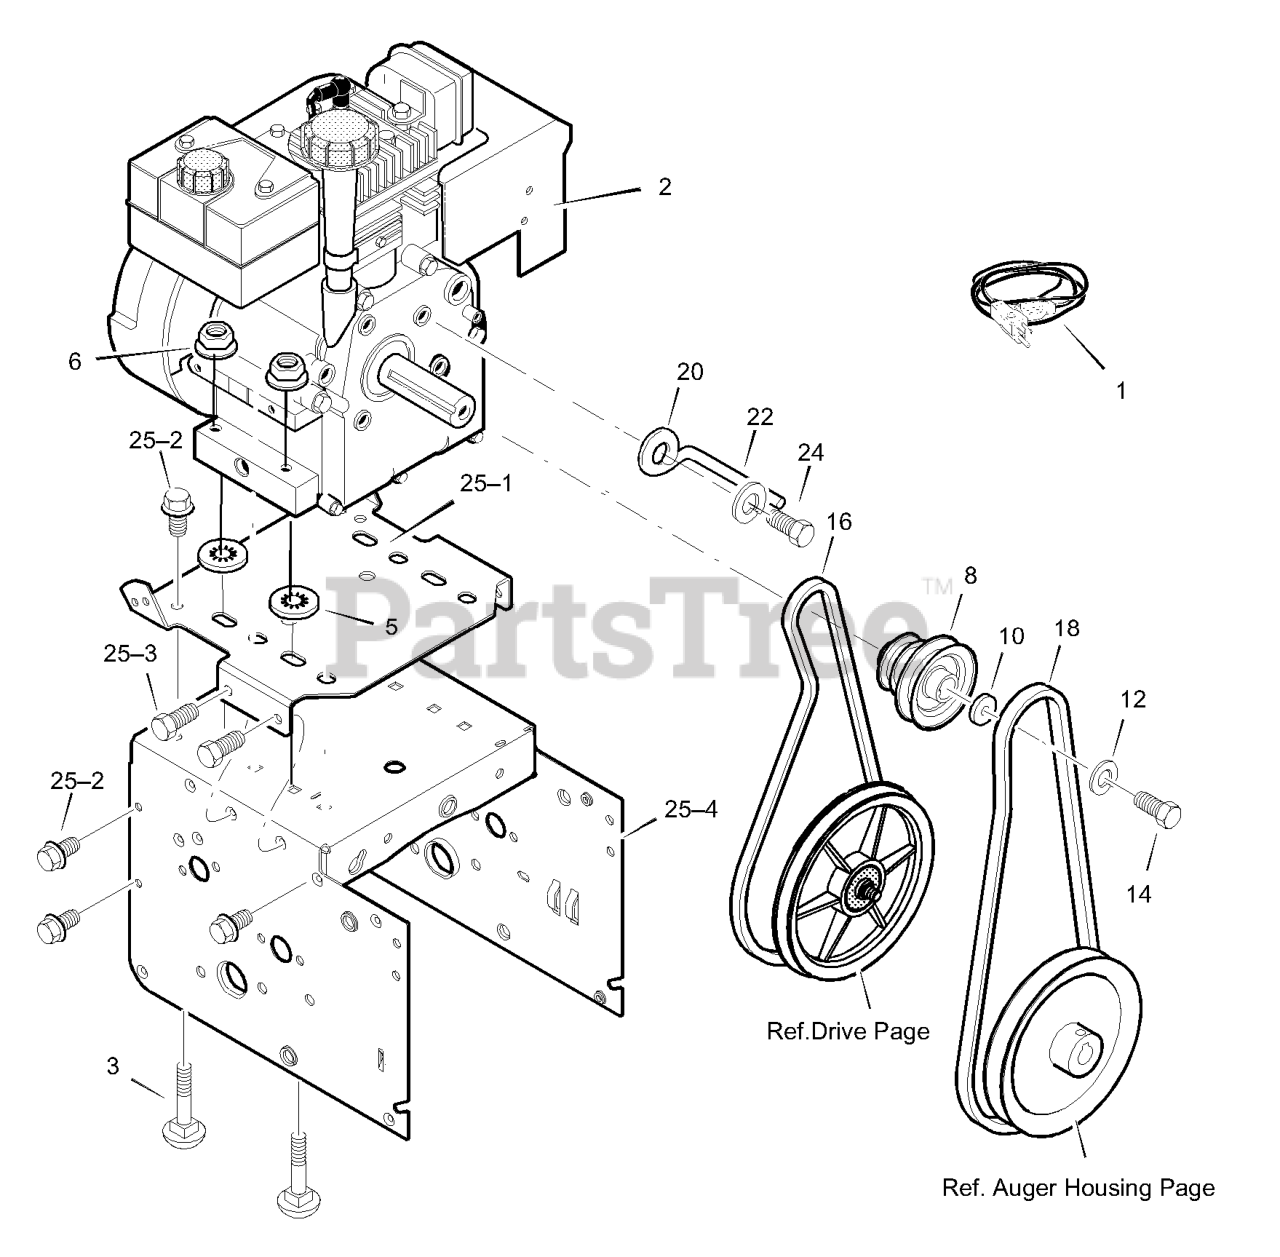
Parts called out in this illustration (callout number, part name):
1	CORD, STARTER MOTOR 220V
2	ENGINE
3	BOLT, CARRIAGE 5/16-18
5	RETAINER, PUSH
6	NUT, HEX 5/16-18
8	PULLEY, ENGINE
10	WASHER
12	WASHER .38ID
14	SCREW, 3/8-24 x 1.00
16	BELT, V 3L 33.13LG
18	BELT, V 4L 38.1MF16" 5-10
20	GUIDE, BELT
22	WASHER, SPTLK .31X.58X.08
24	SCREW, 5/16-24 x 0.75
25	FRAME ASSEMBLY
25-1	PLATE, ENGINE MOUNT
25-2	SCREW, TAP 1/4-20 X .63
25-3	SCREW, TAP 5/16-18 X .50
25-4	FRAME, MOTOR BOX
